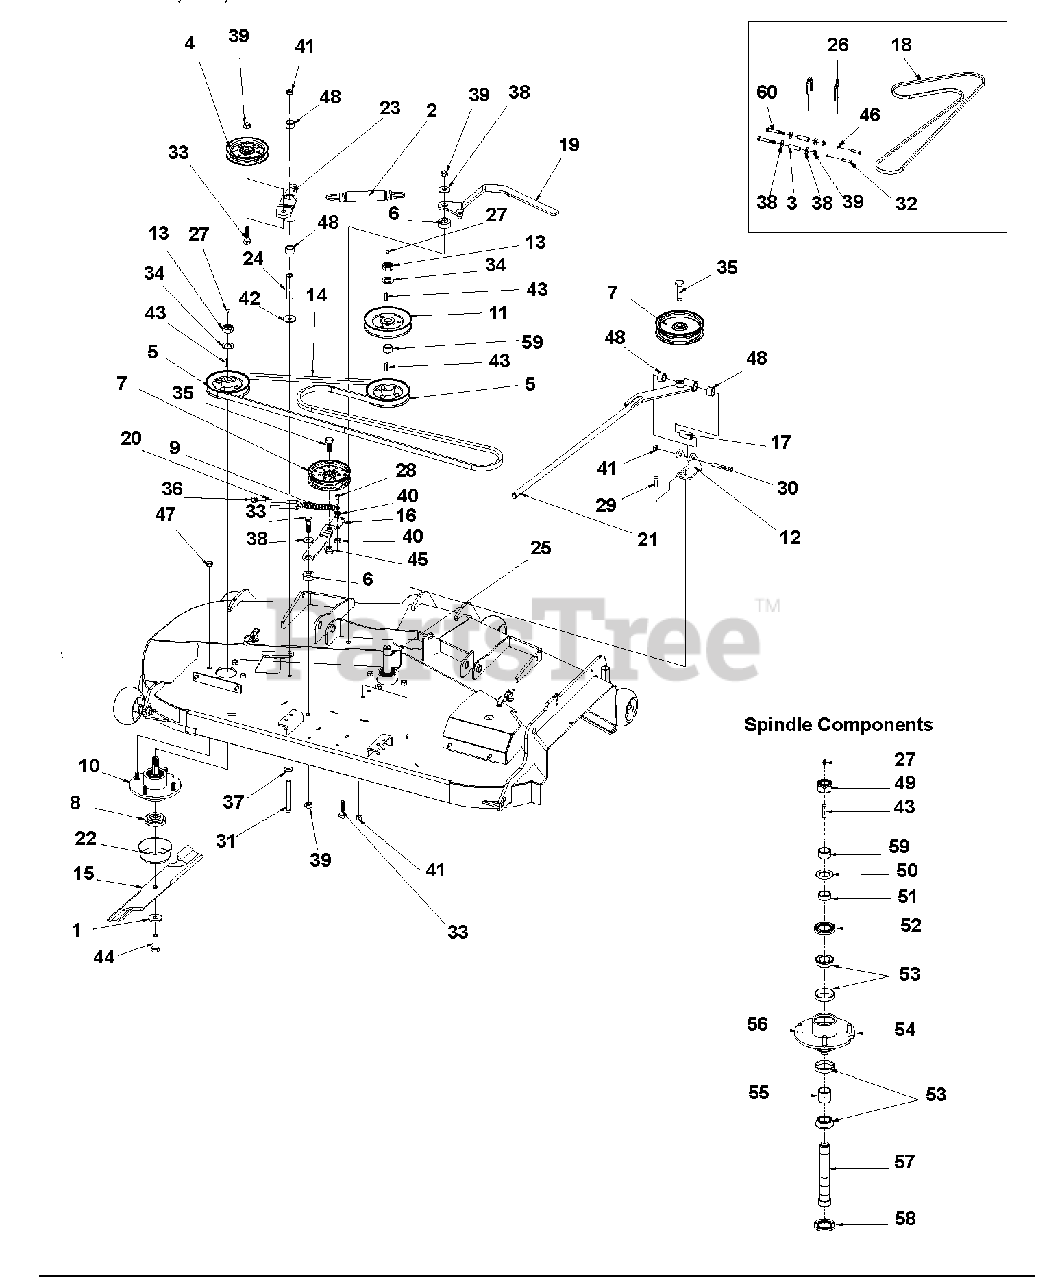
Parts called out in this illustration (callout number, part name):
1	Washer, M14 x M40 x M4.5 FLAT
2	Spring, EXT 1.18 x .177 x 7.50
3	Tube, RD .750 x .125W x 2.469
4	Pulley, V-Belt 5.00 x .510
5	Sheave, 5.00 Spindle (1.00ID)
6	Spacer, Ø.516 x Ø1.50 x .853
7	Pulley, Flat 5.00 x .635 W/BRG
8	Spacer, Blade
9	Spring, EXT .750 x .125 x 4.50
10	Assembly, Spindle 1" SHORT Shaft (includes items 27, 43 and 49 - 59)
11	Pulley, V-Belt 6.75 x 1.0 W/Keyway (992407)
12	Plate, Pivot Anchor Bent
13	Locknut, 3/4-16
14	Belt, B123 - 60" Deck (992407)
15	Blade, 20.940 LO-LIFT - 60" Deck (992407)
16	Arm, Belt Tensioner
18	Belt, HB114.9 EL
19	Weldment, Tension Arm
20	U-Bolt, Round .63 x 4.50 x 3/8-16
21	Weldment, Offset Arm w/Bushings (includes item 48)
22	Cap, Spindle
23	Weldment, Deck Idler Arm w/Bushings (includes item 48)
24	Tube, Ø.750 x Ø.438 x 3.047
25	Assembly, Spindle 1" Long Shaft (includes items 27, 43 and 49 - 59)
26	U-Bolt, Round 1.00 x 3.00 x 3/8-16
27	Fitting, 1/4-28 STRGT Grease Zerk
28	Bolt, 5/16-18 x 1.25 Hex 5
29	Bolt, 3/8-16 x 1.00 Hex 5
30	Bolt, 3/8-16 x 2.50 Hex 5
31	Bolt, 3/8-16 x 4.00 Hex 5
32	Bolt, 7/16-14 x 1.75 Hex 5
33	Bolt, 1/2-13 x 1.75 Hex 5
34	Washer, 1.062 x 1.75 x 0.100
35	Bolt, 5/8-11 x 1.50 Hex 5
36	Nut, 3/8-16 STD Hex GR5
37	Washer, .375 REG Flat
38	Washer, .500 REG Flat
39	Locknut, 1/2-13 Crown
40	Locknut, 5/16-18 Whiz
41	Locknut, 3/8-16 Crown
42	Washer, .375 x 1.50 x .O63 Flat
43	Key, .250 x .250 x 1.00 SQ
44	Bolt, 9/16-12 x 1.75 Hex 8
45	Locknut, 5/8-11 Whiz
46	Locknut, 7/16-14 Whiz
47	Nut, 7/16-20 Hex
48	Bearing, Sleeve .753 x .878 x .750
49	Locknut, 1"
50	Washer, 1.062 x 1.75 x 0.100
51	Spacer, Seal
52	Seal, Upper
53	Bearing Assembly, 1IN Diameter Spindle
54	Casting, Mower Spindle 3.31 LG
55	Pre-Load Spacer, .606
56	Stud, Special 7/16-20
57	Shaft, Spindle - Outside Spindles
58	Seal, Lower
59	Spacer, 1.01 x 1.25 x .635
60	Bolt, .50-13 x 3.50 Hex 5
61	Spindle Bearing Kit (Contains items 52, 53, 55 and 58)
